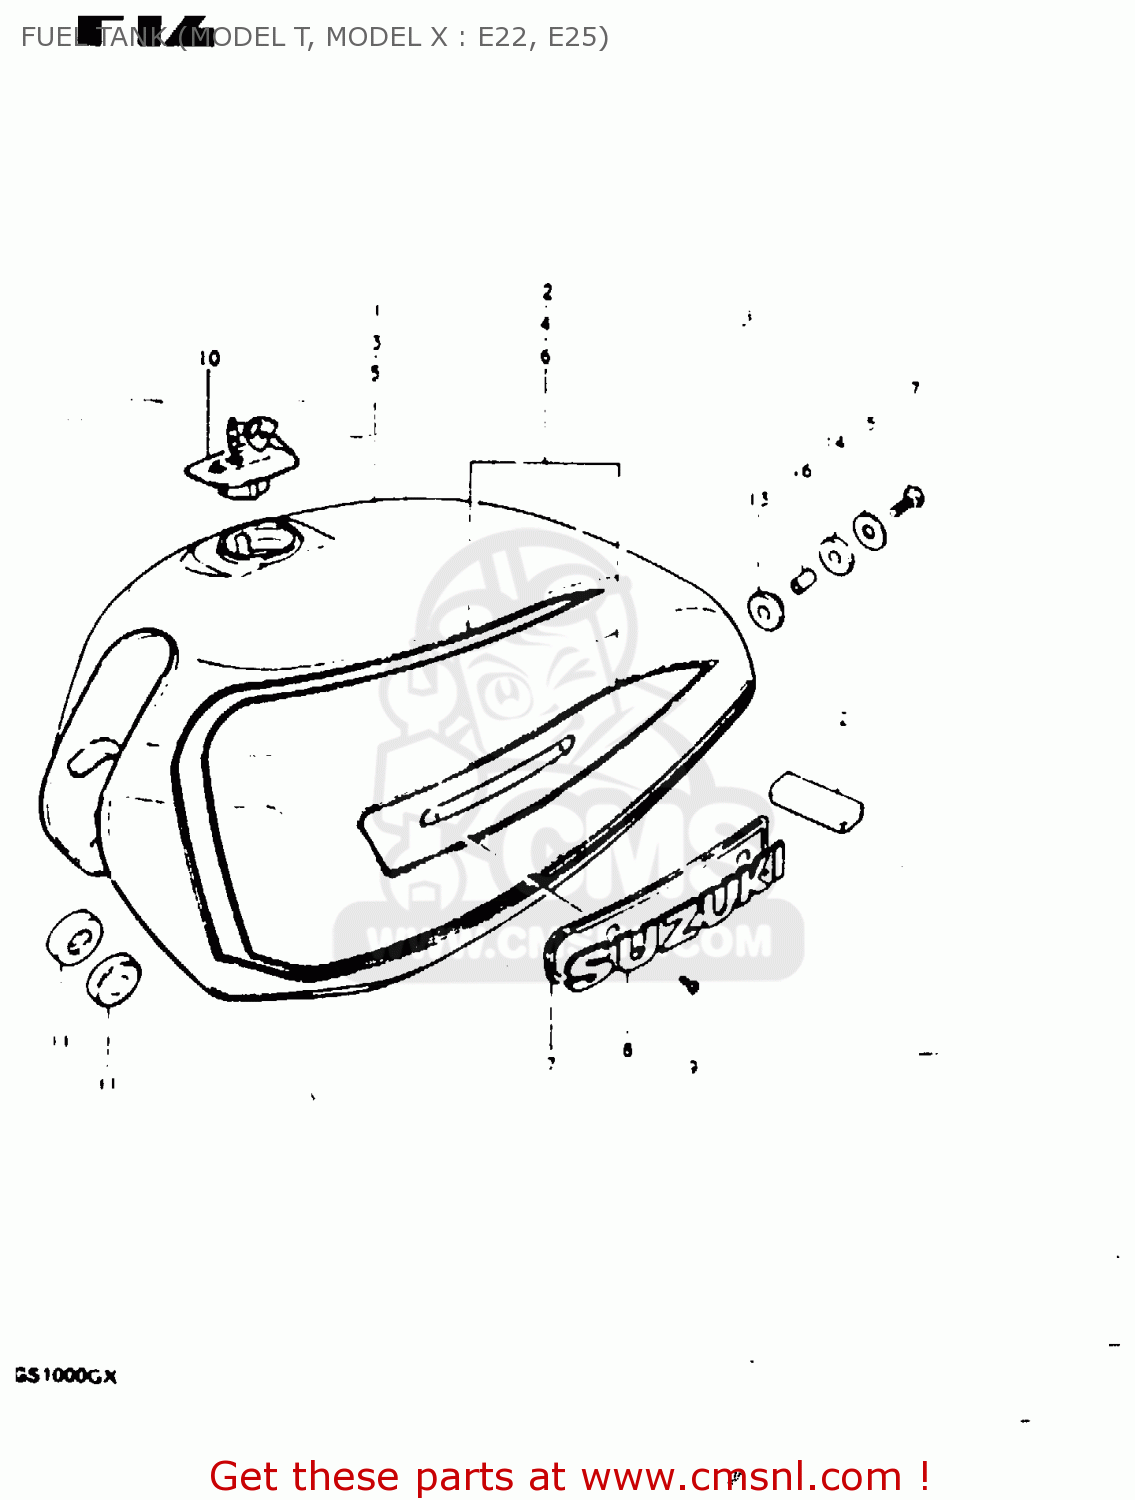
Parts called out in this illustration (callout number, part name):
1	TANK, FUEL (BLACK)
2	TAPE SET
3	TANK, FUEL (SILVER)
4	TAPE SET
5	TANK, FUEL (BLUE)
6	TAPE SET
8	EMBLEM,FUEL TANK
9	SCREW 3X6
10	CAP SET,FUEL TANK
11	CUSHION
12	CUSHION
13	CUSHION
14	CUSHION
15	WASHER (8.5X29X1.6)
16	SPACER(8.5X12X19)
17	BOLT (8X30)
